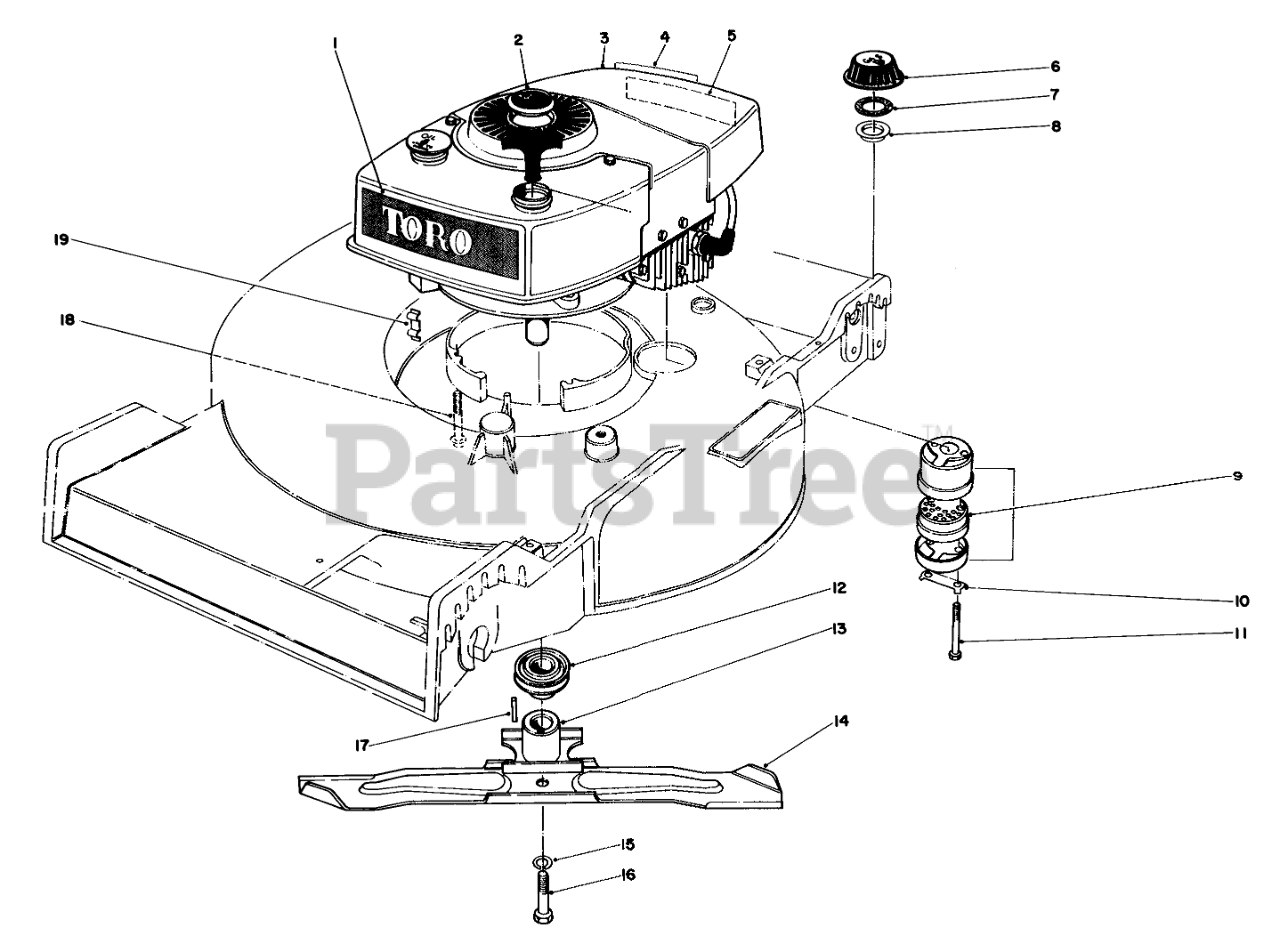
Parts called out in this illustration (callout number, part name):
1	Decal Toro
2	Plug Button
3	Engine
4	Decal-Primer Bulb
5	Decal Maintenance
6	Gas Cap Assembly (Incl. Ref. #7 & 8)
7	GASKET
8	GAS CAP BAFFLE
9	Muffler Assembly (Incl. Ref. #10 & 11)
10	CLIP - LOCKING
11	SCREW-HH
12	Pulley
13	BLADE RETAINER WA(BLACK)
14	Blade
15	WASHER-LOCK
16	BLADE SCREW
17	KEY-SQUARE
18	3/8-16 X 2 CAPSCREW
19	Clip Conduit
